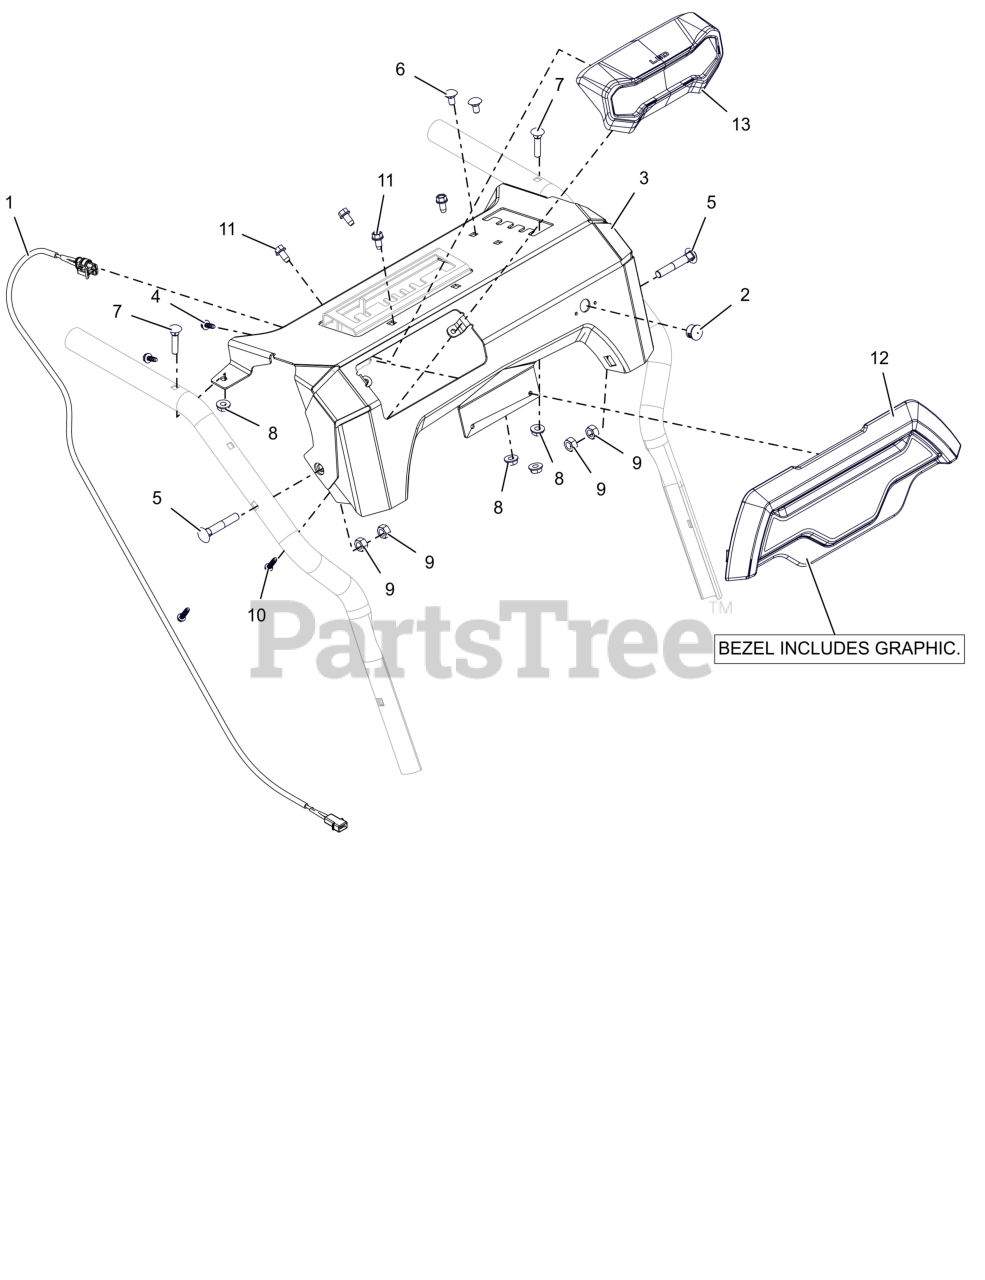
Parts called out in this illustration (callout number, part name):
1	HARNESS- WIRE - LT
2	HOLE PLUG, PLASTIC .56 HOLE
3	PANEL, DASH - COMPACT
4	SCR, PLASTIC #10X.50
5	BLT-RDHDXLSQNK .31-18X2.0 G5YZ
6	BLT, RHSN .25-20X.500 G5 ZCC
7	BLT-RDHDXLSQNK.25-20X1.25 G5ZC
8	NUT-LK-CTR-FLG .25-20 ZC120
9	NUT,LK-CTR .31-18 GA ZCC
10	SCR-HWH 10-16X.75 HI-LO ZCC
11	SCR-TAP .25-20X.50 HWH ZCC
12	BEZEL, SMALL - COMPACT
13	HEADLIGHT ASM- LED
